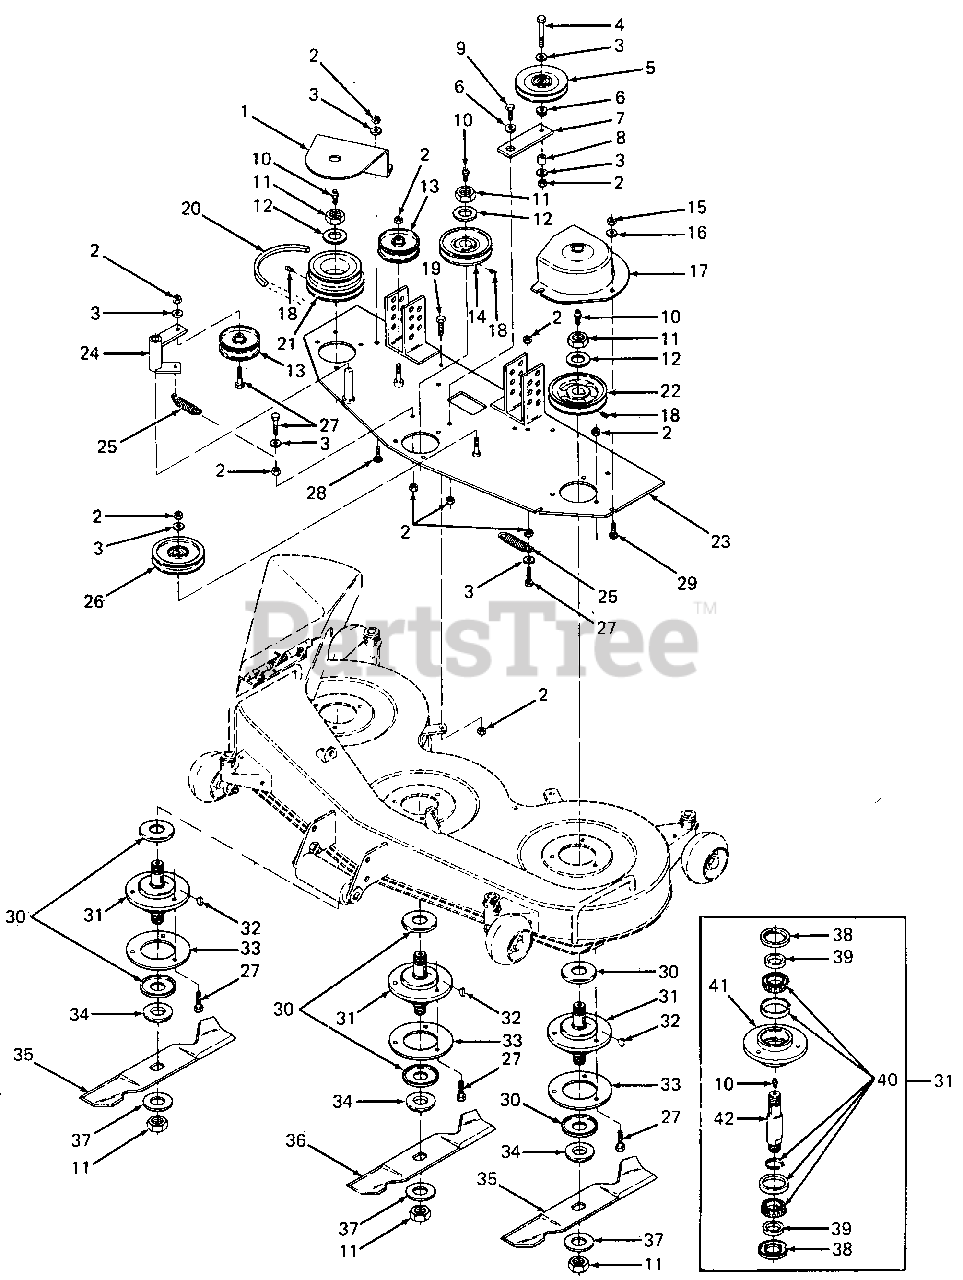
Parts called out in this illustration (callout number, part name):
1	Guard, Belt, RH
2	Nut, Hex Center Lock, 3/8-16
3	Washer, Flat, .385 X .870 X .090 Thk
4	Screw, Hex Cap, 3/8-16 X 2.75 Lg
5	Pulley, Idler
6	Spacer, Flanged
9	Screw, Hex Cap, 3/8-16 X 7/8 Lg GR8
10	Fitting, Grease
11	Nut, Hex Jam, 1/8
12	Washer, Flat, 1 Narrow
13	Pulley, Idler
14	Pulley, Spindle, Center
15	Nut, Hex Center Lock, 5/16-18
16	Washer, Flat, .344 X .875 X .063 Thk
17	Guard, Belt, LH
18	Setscrew, 5/16-18 X 3/8 Cup/Knurl
19	Screw, Hex Cap, 3/8-16 X 1 Lg GR5
21	Pulley, Double Groove
22	Pulley, Deck
23	Plate, Deck
25	Spring, Idler Extension
26	Pulley, Idler
27	Screw, Hex Cap, 3/8-16 X 1-1/2 Lg GR5
28	Bolt, Carriage, 3/8-16 x 1 Lg
29	Bolt, Carriage, 5/16-18 X 3/4 Lg
30	Shield, Bearing
31	Spindle Assy
32	Key, Woodruff, Hi-Pro
33	Ring, Spindle Reinforcement
34	Ring, Blade Support
35	Blade, Mower, 16.28 Lg
36	Blade, Mower, 14.88 Lg
37	Washer, Flat, 1 Wide Zinc
40	Bearing Assy, Tapered
41	Housing, Spindle
42	Shaft, Spindle
